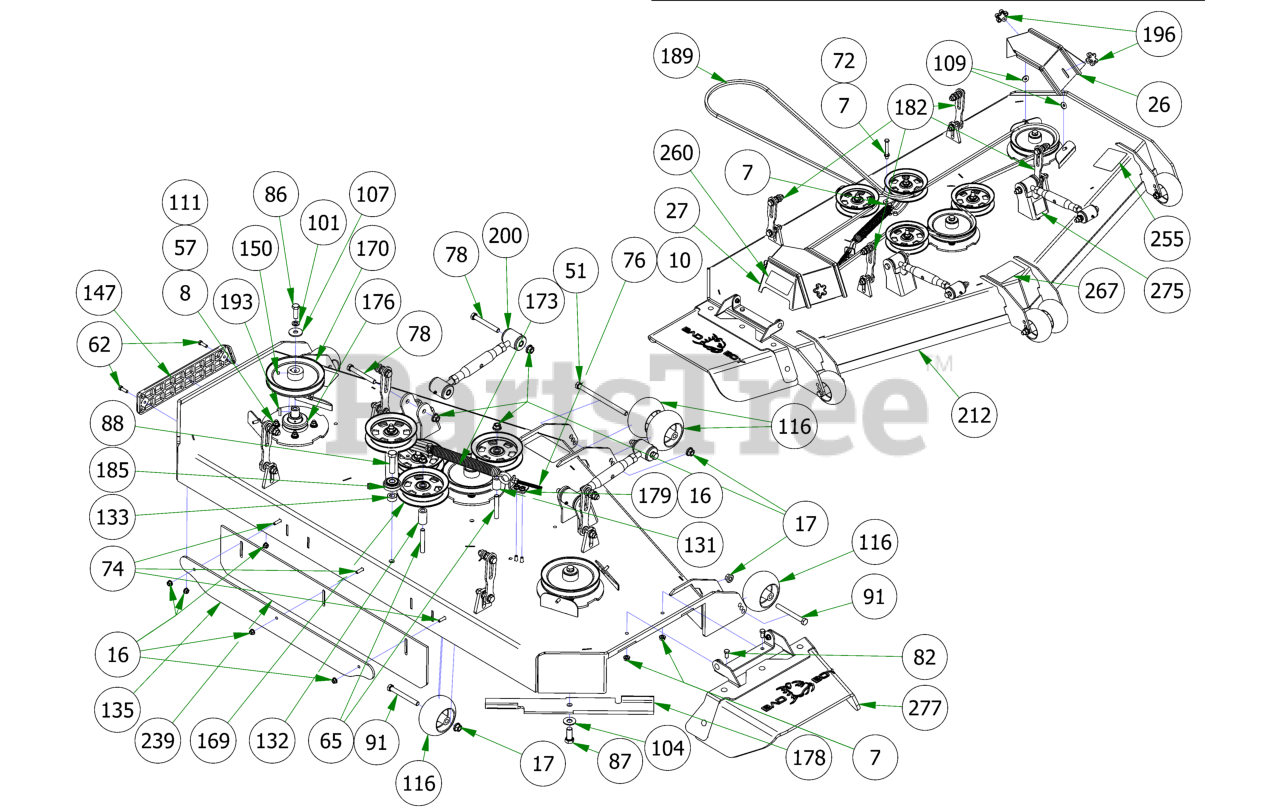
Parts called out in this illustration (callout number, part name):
7	3/8-16 HEX SERRATED FLANGE NUT HARD/ZINC
8	3/8-16 NYLON INSERT FLANGE LOCKNUT (GR.F) ZINC
10	3/8-16 HEX NUT ZINC
13	5/8-11 NYLON INSERT LOCKNUT ZINC
16	5/16-18 NYLON INSERT FLANGE LOCKNUT ZINC
17	1/2-13 NYLON INSERT FLANGE LOCKNUT ZINC
26	2019 72" Left Outlaw Gen2 Pulley Cover
27	2019 72" Right Outlaw Gen2 Pulley Cover
51	1/2-13 X 8 HEX CAP SCREW GR 5 ZINC
57	3/8-16 X 1-3/4 HEX C/S (GR.5) ZC
62	5/16-18 X 1 HEX CAP SCREW (GR.5) ZINC
65	1/2-13 X 3-1/2 HEX FLANGE BOLT (GR.8) ZINC
72	3/8-16 X 3 HEX CAP SCREW (GR.5) ZINC
74	5/16-18 X 1-1/4 CARRIAGE BOLT ZINC
76	4" 3/8-16 Eye Bolt
78	1/2-13 X 4 HEX CAP SCREW (GR.8) ZINC YELLOW
82	3/8-16 X 3/4 HEX CAP SCREW (GR.5) ZINC
86	1/2-20 X 1-1/2 HEX CAP SCREW (GR.5) ZINC
87	5/8-18 X 1-1/2 HEX CAP SCREW (GR.8) ZINC YELLOW
88	5/8-11 X 2-1/2 HEX CAP SCREW (GR.5) ZINC
91	1/2-13 X 4-1/2 HEX CAP SCREW (GR.5) ZINC
97	5/16-18 X 7/8 CARRIAGE BOLT ZINC
101	1/2 SPLIT LOCKWASHER (GR.8) ZINC/YELLOW
104	5/8 USS FLAT WASHER (1-3/4" OD) GR.8 ZINC YELLOW
107	1/2 BELLEVILLE WASHER (1-5/8 OD X .140 THK) ZINC
109	.360 ID X .983 OD X .120 THICK FLAT WASHER NYLON BLACK
111	5/16 USS FLAT WASHER (7/8 OD) ZINC
116	2019 Deck Wheel
131	.502 ID X .750 OD X 1.500 Long Spacer
132	1 3/4" Pulley Spacer
133	5/8 SOLID SHAFT COLLAR (W/1 SET SCREW) ZINC
135	61 Bolt in Baffle Deck v2 Stripping Plate
147	REVISED TRIM BUMPER_20180226
150	5/16-24 X 1/4 SOCKET SET SCREW (CUP PT) PLAIN
169	5-3/4 Idler Pulley
170	7" Deck Pulley
173	2019 Outlaw Gen2 Deck Spring
176	OUTLAW SPINDLE ASSEMBLY
178	72" High Lift Fusion Blade
179	2019 Deck Eye Bolt Tab
182	Deck Hanger Assembly
185	2019 Renegade Deck Idler
189	Belt for 72" Renegade
193	1/4 X 1 SQ MACHINERY KEY 1018 STL PLN
196	5/16" Knob
200	Turnbuckle
212	2019 Sloped 72" Deck
239	R Series Rubber For Deck
255	2018 72" Deck Decal
260	Danger Decal-Spindle/Discharge
267	2019 Renegade Deck Belt Route Decal
275	Deck Impact Patent Decal 9591803
277	2019 Outlaw Gen2 Chute Assembly
